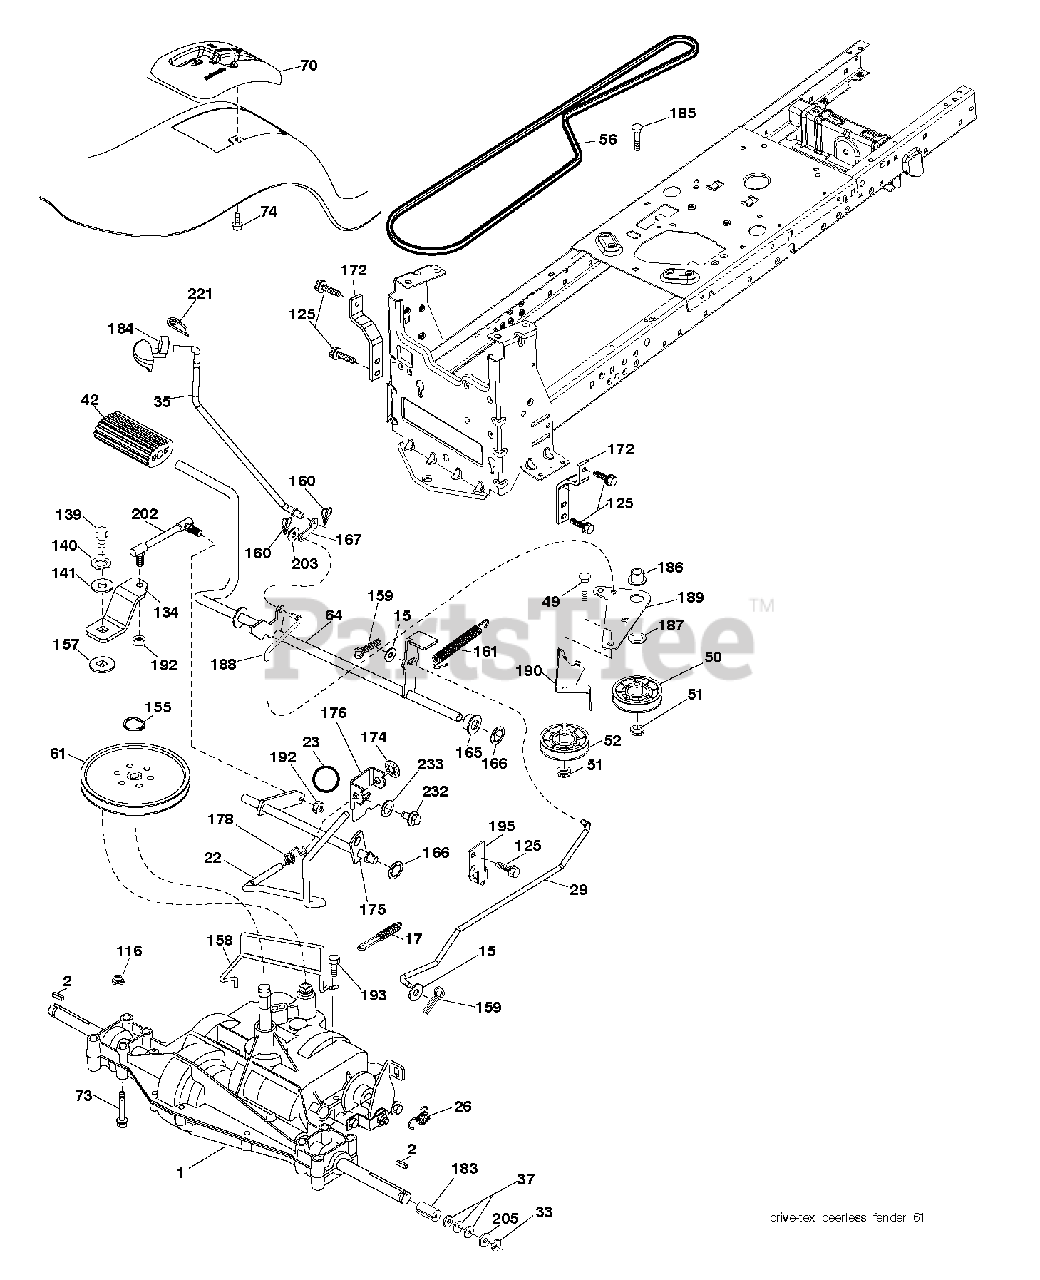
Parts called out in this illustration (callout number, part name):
2	SQUARE KEY
17	SPRING.BRAKE.PEERLESS.TEX
22	ROD.SHIFT.FENDER.TLT.2006
23	KNOB T (1/2-HOLE)
26	SPRING.BRAKE.RTN.GR.DR
29	ROD.BRAKE.PEERLESS
33	E-RING LT
35	ROD.BRAKE.PARKING.LT.T
49	BOLT
50	IDLER.FLAT.910.OFFSET
51	NUT LOCK FLG 3/8-16 UNC
52	IDLER.V-GROOVE.910.OFFSET
56	V-BELT.TRACTOR.DRIVE.P
61	PULLEY TRANS
64	SHAFT.ASM.PEDAL.BRAKE.
70	CONSOLE.SHIFT.STL.6SP.BLACK.T
73	BOLT HEX 5/16-18 GR 5
74	SCREW.HI-LO.CONSOLE
116	NUT LOCK HEX FLANGE 5/16-18
125	SCREW
134	ARM.SHIFT.T/A.PMST.20"
139	Bolt, 1/4-20 unf Grade 8 w/Patch
140	LOCKWASHER
141	WASHER LT
155	RETAINING RING LT
157	WASH-SHFT PLT LT
158	KEEPER.PMS.18/20.D4365
159	COTTER PIN
160	RETAINER CLIP
161	SPRING, RETURN LT
165	BUSHING.SHAFT.BRAKE.HAND
166	NUT.PUSH.625
167	LATCH.BRAKE.SPRING
172	STRAP.TORQUE.VARIATOR
174	NUT.PUSH.500.2006
175	SHAFT.ASM.SHIFT.GEAR.D
176	ARM.CLEVIS.ROD.SHIFT
178	SPRING.SHIFT.GT2006
183	SPACER AXLE
184	BOOT.STEERING.LT.TEX.P/L.418
186	SPACER.RETAINER
187	WASHER 12/32X2X10GA
188	LINK.CLUTCH.GROUND.DRIVE
189	BELLCRANK.GROUND.DRIVE.TEX.
190	KEEPER.BELLCRANK.DRIVE
192	NUT LOCK CENTER 1/4 -28 FNTHD
193	SCREW 5/16"
195	BRKT.ROD.BRAKE.PEERLES
202	LINK.TRANSAXLE.PMST/DANA.20"
203	WASHER
221	RETAINER.SPRING.CLIP.H
232	BOLT FIN HEX 7/16-14 X 1
233	WASHER SERRATED
